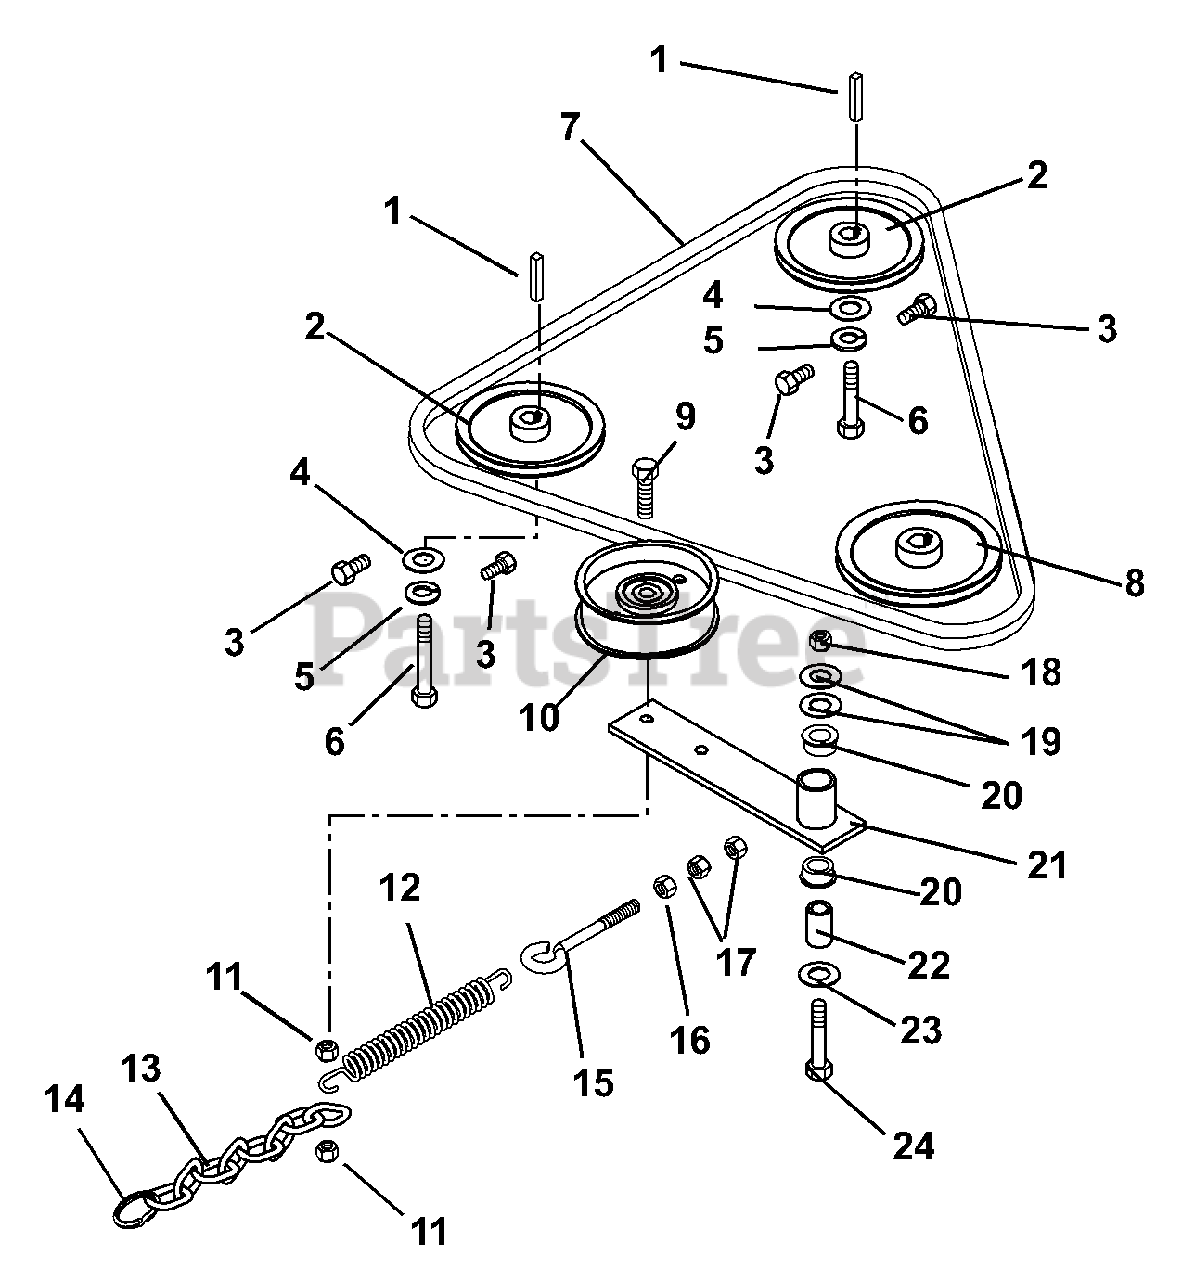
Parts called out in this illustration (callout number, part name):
1	KEY-STR 5MMX25MMX5MM
2	SHEAVE, PUMP .592 X 4.345
3	@BLT-HEX .25-20X.50 GR5 YWZC
4	WSHR-FL-STL .281X1.250X.048PL
5	@WSHR-LK .25X.062 REG YWZC
6	BLT-HEX M6 X 1.0X12 YWZC
7	V-BELT, 4L-RAW EDGE
9	@BLT-HEX .38-16X2.00 GR5 YWZC
10	IDLER-PLY FLAT 3.25 X .38 X1.0
11	@NUT-LK-CTR-JAM .375-16 YWZC
12	SPRING, EXT
13	CHAIN, LINK
14	RING, SPLIT .1 X 2
15	BLT-EYE .375-16X2.50 YWZC
16	@NUT-HEX .38-16 YWZC
17	@NUT-LK-NYL .38-16 YWZC
18	@NUT-LK-NYL .50-13 YWZC
19	@WSHR-FL-STL.531X1.06X.095YWZC
20	BSHG-FLG .762X1.0X.580X1.48 NY
21	WLDMT,GROUND DRIVE IDLER
22	BUSH.,S.560X.745X2.04 ST
23	@WSHR-FL-STL.531X1.06X.095YWZC
24	@BLT-HEX .50-13X3.25 GR5 YWZC
